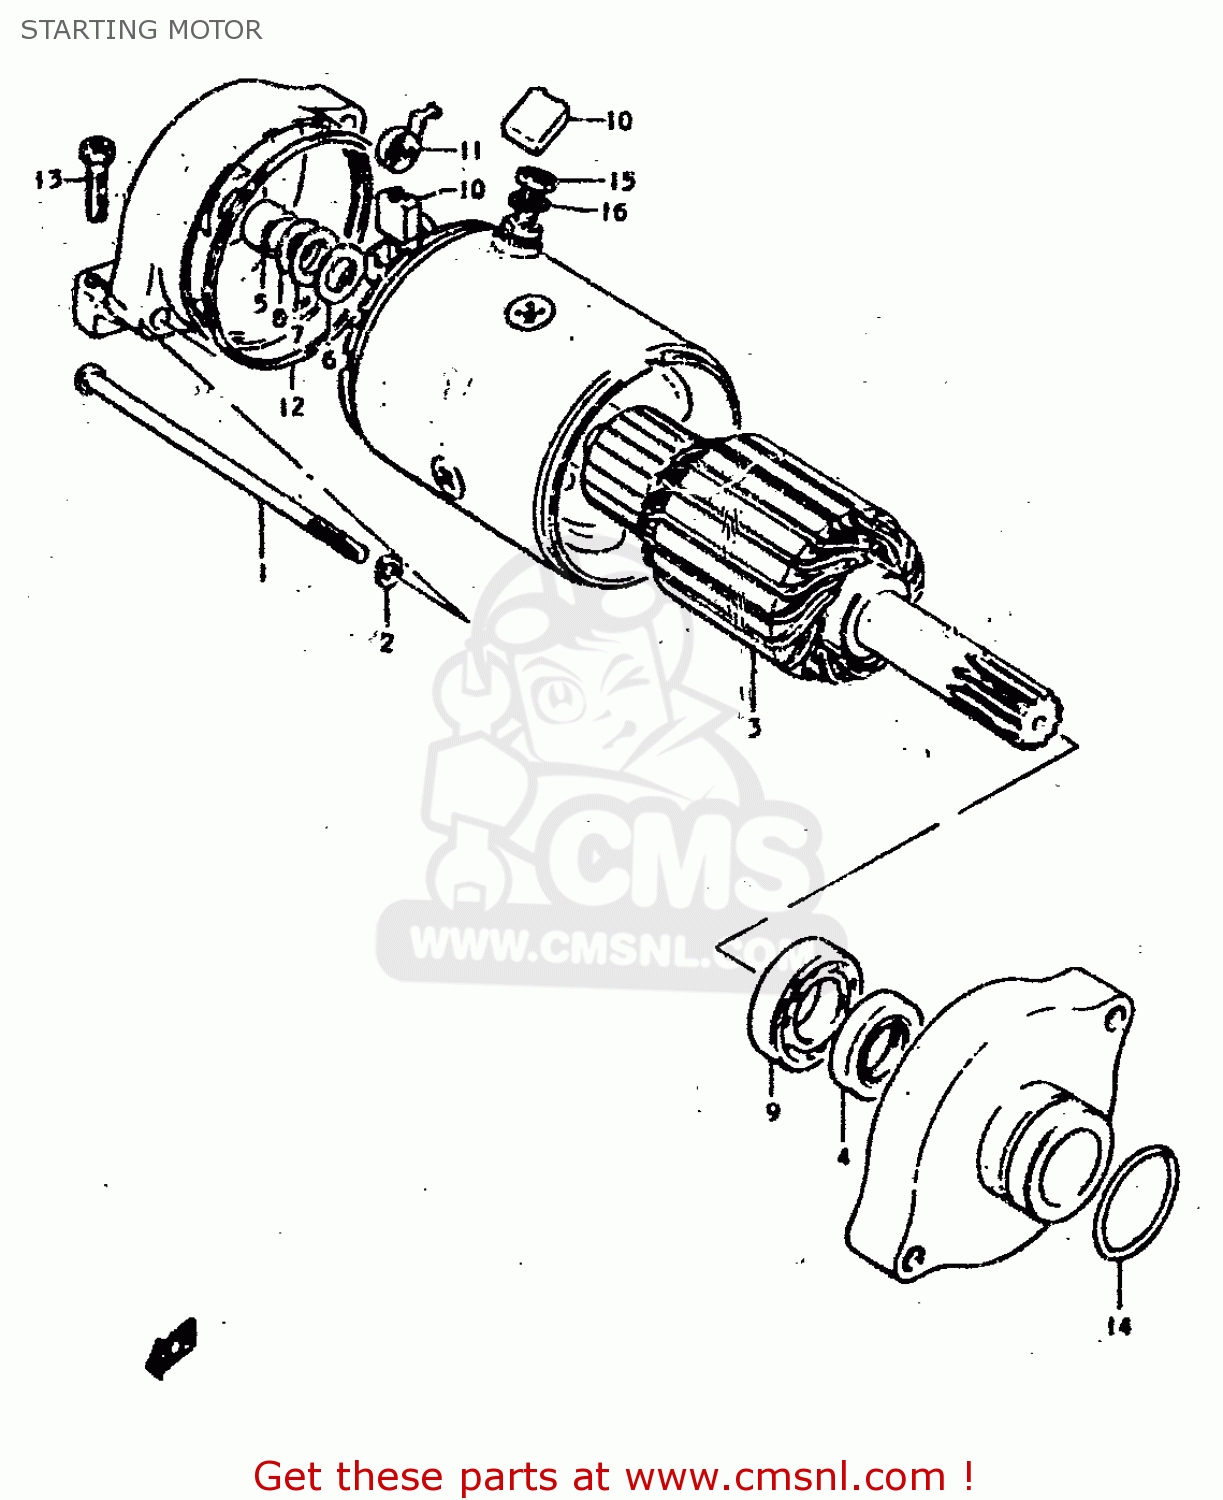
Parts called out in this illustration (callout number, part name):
1	BOLT
2	LOCK WASHER
3	ARMATURE
4	SEAL,OIL
5	BUSHING
6	SHIM, (1)
7	SHIM, (2)
8	SHIM, (3)
9	BEARING
10	BRUSH(-)
11	SPRING
12	GASKET
13	SCREW(6X10)
14	O RING(D:2,ID:24.5)
15	NUT 6MM
16	LOCK WASHER
